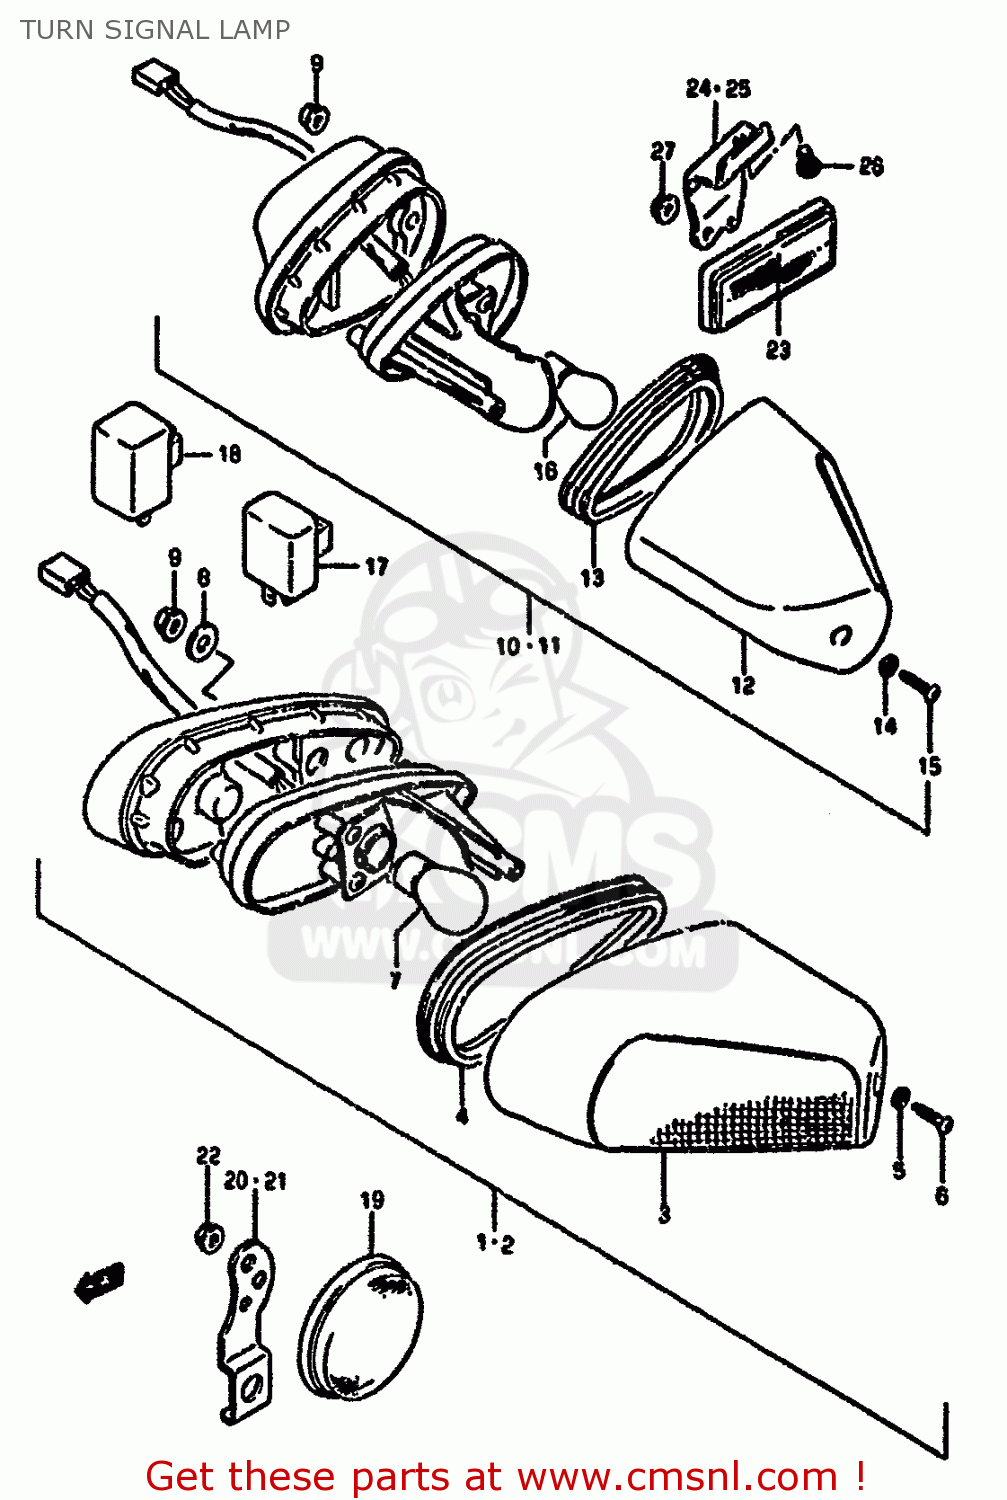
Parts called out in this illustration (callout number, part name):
1	LAMP ASSY,FR TURN SIGNAL,R
2	LAMP ASSY,FR TURN SIGNAL,L
3	LENS
4	GASKET (NAS)
5	GASKET (NAS)
6	SCREW 4X16
7	BULB(12V21W)
8	WASHER (6.5X18X1.6)
9	NUT
10	LAMP ASSY,REAR TURN RH
11	LAMP ASSY,RR T
12	LENS
13	GASKET (NAS)
14	GASKET (NAS)
15	SCREW 4X16
16	BULB(12V21W)
17	RELAY ASSEMBLY,TURN SIGNAL
18	RELAY ASSY,TUR
19	REFLECTOR,REFLEX FR
20	BRACKET,FRONT SIDE,REAR
21	BRACKET,FR SIDE RR,L
22	NUT
23	REFLEX REFLECTOR,FR SIDE
24	BRACKET,RR SIDE RR,R
25	BRACKET,RR SIDE RR,L
26	SCREW 6X12
27	NUT
